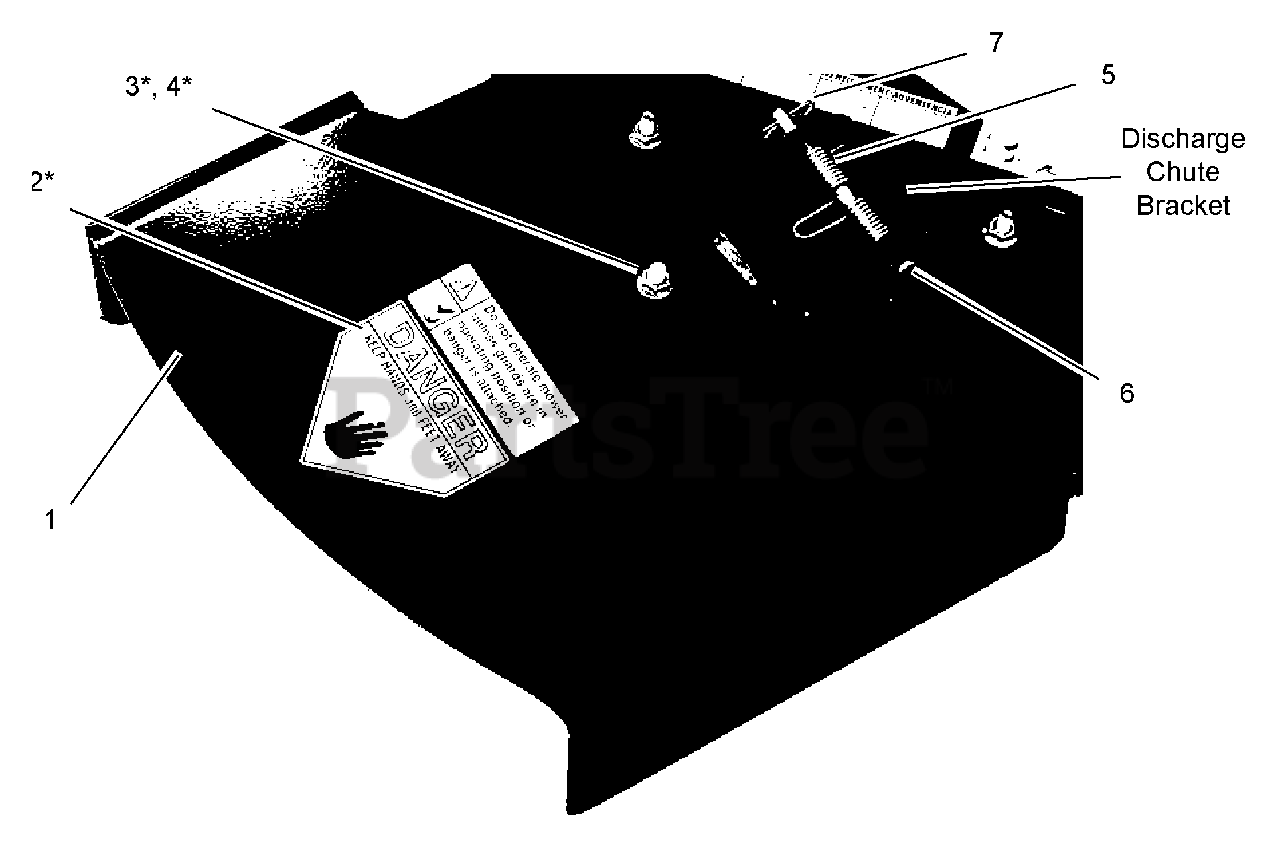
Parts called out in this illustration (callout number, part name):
1	Steel Discharge Chute
2	Danger Decal
3	Rubber Bumper
4	5/16" Locknut
5	Torsion Spring
6	Clevis Pin
7	Hair Pin
